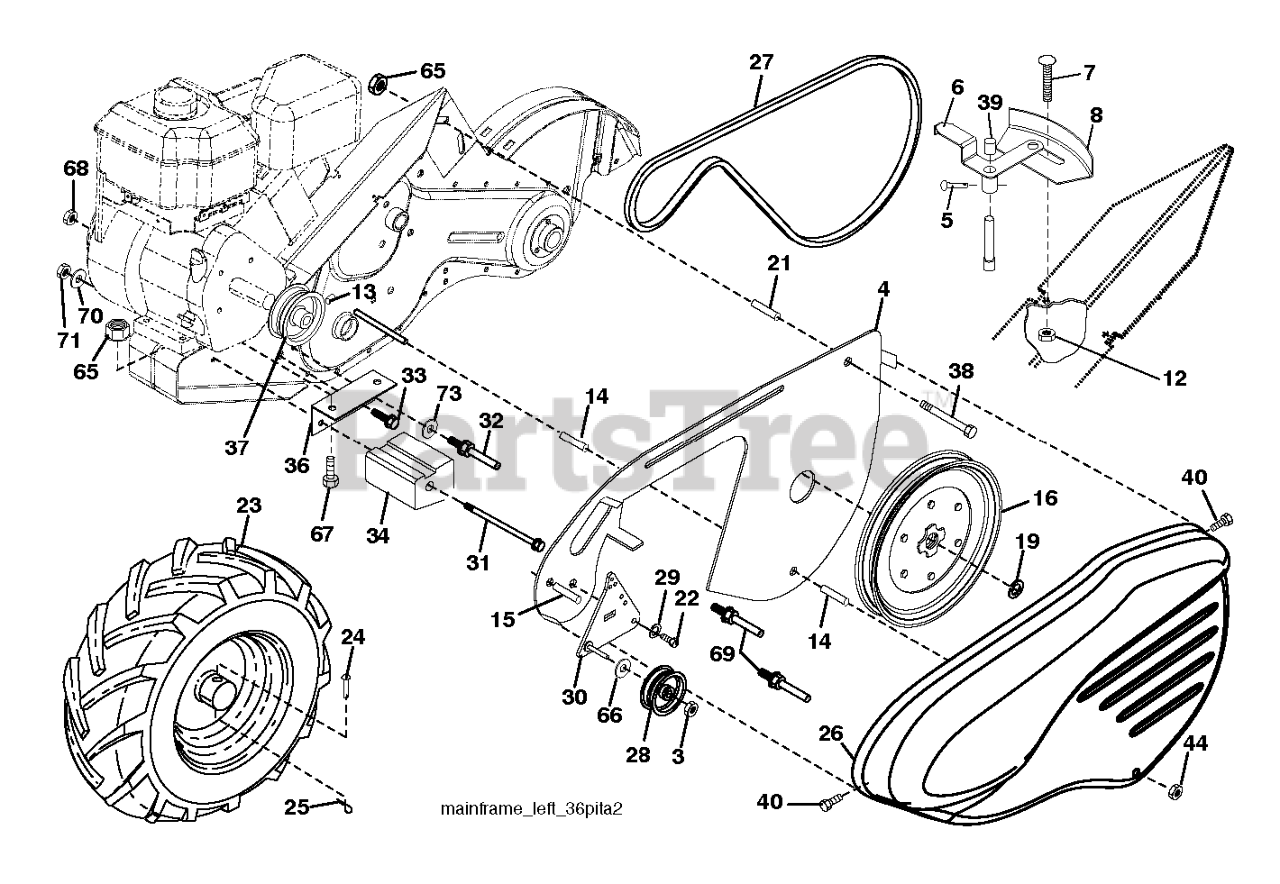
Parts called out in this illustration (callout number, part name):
3	LOCKNUT
4	SHIELD.INNER.BELT.GUARD.RT.BLA
5	PIN.SPIROL.FLARED
6	LEVER ASM CRT
8	PANEL.INDICATOR.SHIFT.BLACK
12	NUT
14	SPACER-SPLIT.327 X .42
16	SHEAVE, TRANSMISSION
19	RETAINING RING LT
21	SPACER SPLIT .420 X .327
23	WHEEL 16X4X8 DR TILLER LH.417
24	RIVET
25	RETAINER M
26	GUARD.BELT.TILLER.ORANGE
27	V-BELT
28	PULLEY-IDLER TI
30	BRACKET.IDLER.ASM.LONG
31	BOLT.FIN.HEX.3/8-16UNC X 11.5
32	SHIFT ARM CRT
33	BOLT
34	COUNTERWEIGHT.LH
36	BRACKET.REINFORCEMENT.LH.PNT
37	RP.ENGINE PULLEY
38	BOLT
39	CAP.PLUNGER.BLACK
40	SCREW.HEX.WSH.SLT.#10-24X.50
44	NUT.71038.31-18.HEX.NYLOCK
65	LOCKNUT-FLANGE 5/16-18
66	WASHER
67	BOLT, HEX 5/16-18X1-3/4
69	KEEPER.BELT.ENGINE
70	WASHER
73	WASHER
